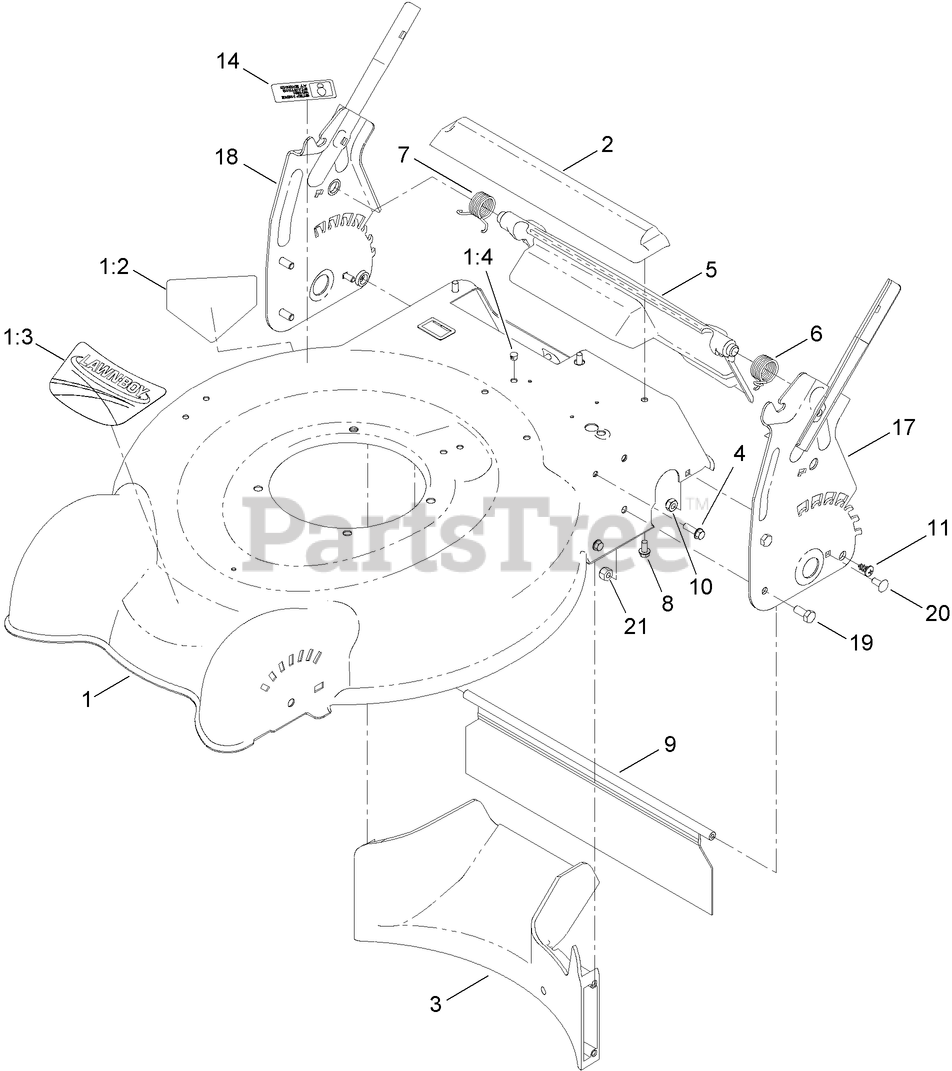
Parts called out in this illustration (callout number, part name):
1	HOUSING ASM
1:2	DECAL-DANGER
1:4	PLUG-DOME
2	CHUTE-REAR
3	BAFFLE-REAR
4	SCREW-HWH
5	REAR DEFLECTOR ASM
6	SPRING-TORSION, LH
7	SPRING-TORSION, RH
8	SCREW-PLASTITE
9	SHIELD-TRAILING
10	NUT-LOCK, NI
11	SCREW-PTH
14	DECAL-PLACEMENT, FOOT
19	SCREW-HH
20	SCREW-CARR
21	NUT-LOCK, NI
